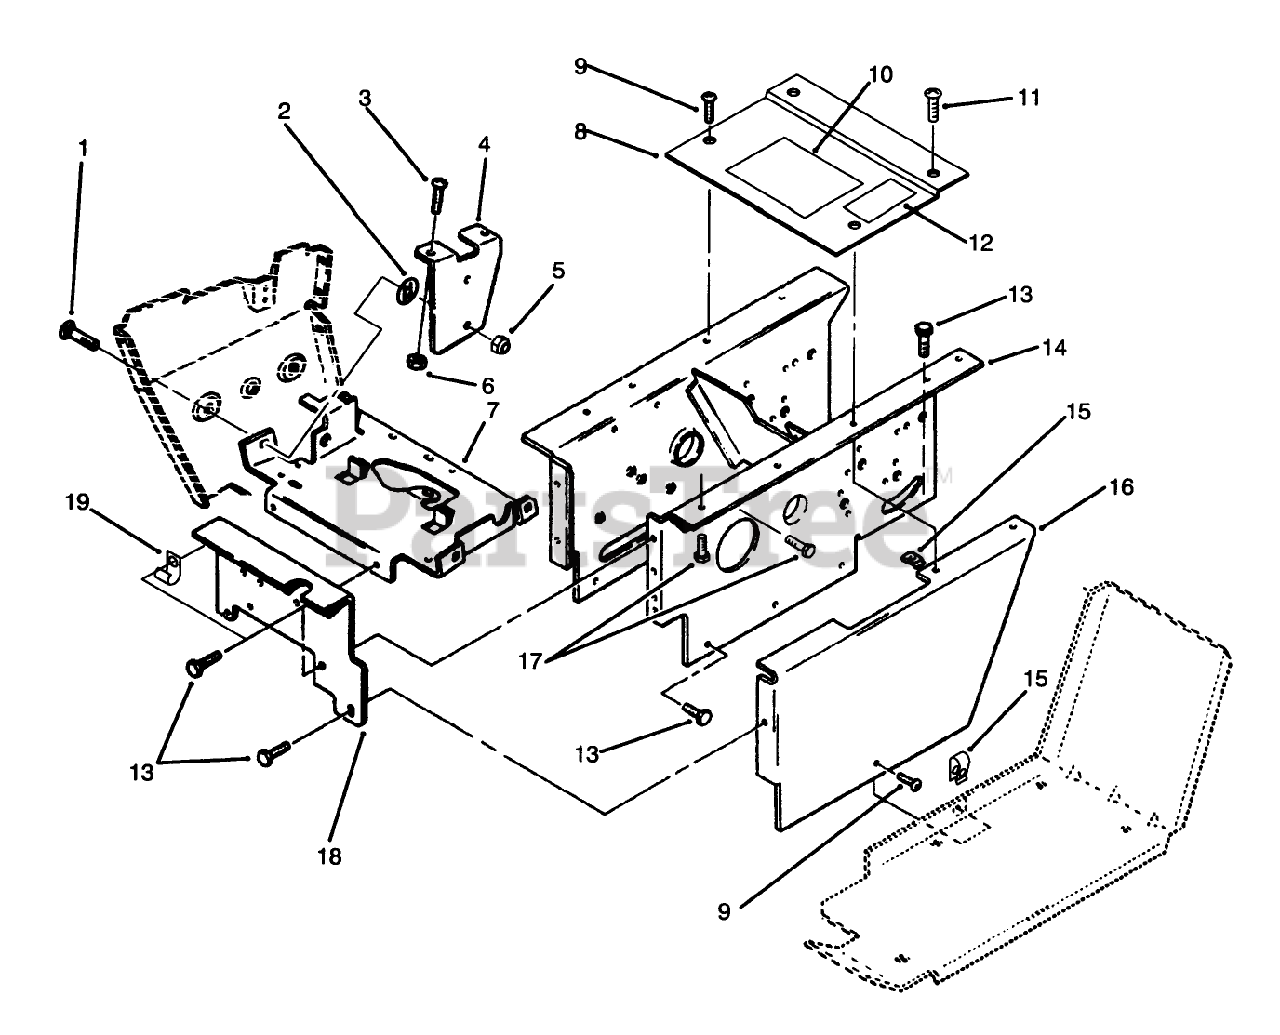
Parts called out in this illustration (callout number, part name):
1	BOLT-CARR
3	SCREW-HH
5	NUT-LOCK, NI
7	WLD-SUPPORT*B
10	DECAL-DANGER
12	DECAL-PARKING BRAKE
13	SCREW
17	SCREW-HH
19	CLIP
